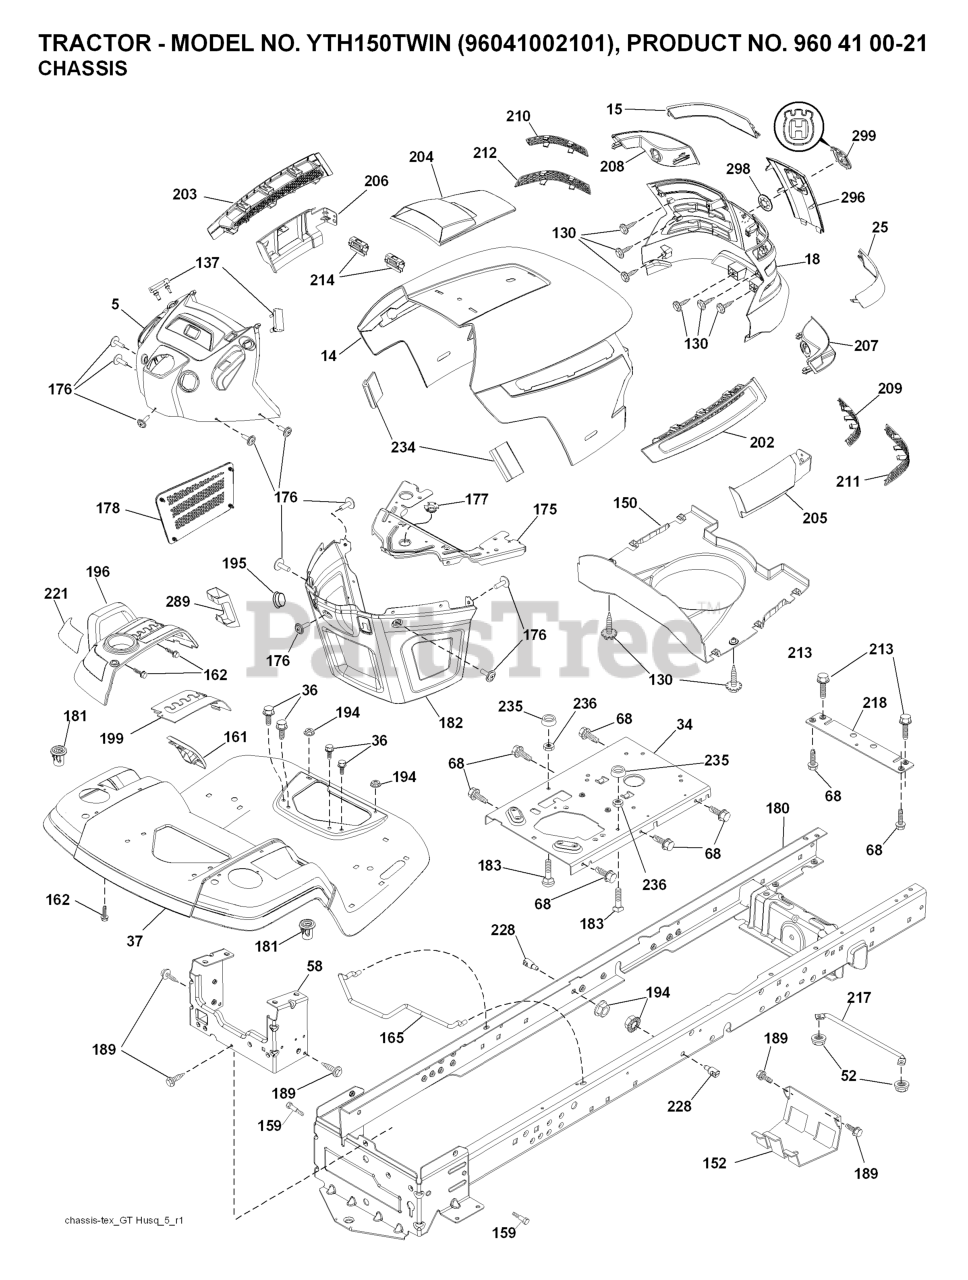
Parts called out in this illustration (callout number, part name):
5	DASH.ASM.HUSQ.GT.E.RECT.W/CK
14	HOOD
15	LENS.LH.TEX.GT.HUSQ.CL
18	GRILL.ASM.HUSQ.TG/CRD.W/TRIM
25	LENS.RH.TEX.GT.HUSQ.CL
34	PLATE.ENGINE.WELDED.CHASSIS
36	SCREW 5/16"
37	FENDER.PNT.TX.GT.CH/FW.ORANGE
52	LOCKNUT
68	Screw 5/16-18 x 1/2 Hex, Self Tapping 5/16-18 x 1/2
130	SCREW
137	BUMPER DASH
150	AIR.DUCT.TEXGT.HUSQ.31
152	SHIELD.BROWNING.W/TEX
159	SCREW, 3/8-16X3/4
161	CONSOLE.FUEL.WINDOW.HU
162	SCREW.HI-LO.CONSOLE
165	SUPPORT.TANK.REAR.W/TEX
175	PLATE.CROSSMEMBER.HUSQ
176	SCREW.#10-24X5/8.RN.QU
177	BUSHING, STEERING
178	CARGO.ASM.NET.TXGT.W/C
180	CHASS.WLDMNT.TLT.12GA/2PC.20"
181	BUSHING.MNT.FEND.CRGO.
182	DASH.LOWER.COMMON.12V.ADAPTOR
183	BOLT.5/16-18X1-1/4 FULL.THREAD
189	SCREW
194	NUT LOCK HEX FLANGE 5/16-18
195	PLUG.HOLE.DASH.LOWER.12V.BLK
196	RP CONSOLE.ASM.DECKLFT.W/
199	PLATE.DECK.LIFT.HUSQVARNA.GT
202	VENT.SIDE.HOOD.HUSQ.RH.GREY
203	VENT.SIDE.HOOD.HUSQ.LH.GRAY
204	HOOD VENT
205	SKIRT.HOOD.SIDE.HUSQ.RH.GREY
206	SKIRT.HOOD.SIDE.HUSQ.LH.GREY
207	BEZEL.RH.TEX.GT.HUSQ
208	BEZEL.LH.TEX.GT.HUSQ
209	INSERT.HEX.GRILL.HUSQ.GREY
210	INSERT.HEX.GRILL.HUSQ.
211	INSERT.HEX.GRILL.HUSQ.
212	INSERT.HEX.GRILL.HUSQ.
213	BOLT
214	CLIP.RETAINER.TINNER.
217	ROD.PIVOT.HOOD
218	X-PIECE.HOOD.STOP.NON/
221	REFLECTOR.LH.TEX GT HU
228	STUD.FASTNER.W/ANTI-ROTATE
235	SPACER FENDER
236	NUT.CENTERLOCK.5/16-
289	PLUG.N/CRUISE.COMMON.YT/GT.BLK
296	TRIM.HUSQ.TG/CRD.SERVICE
298	NUT PUSH M
